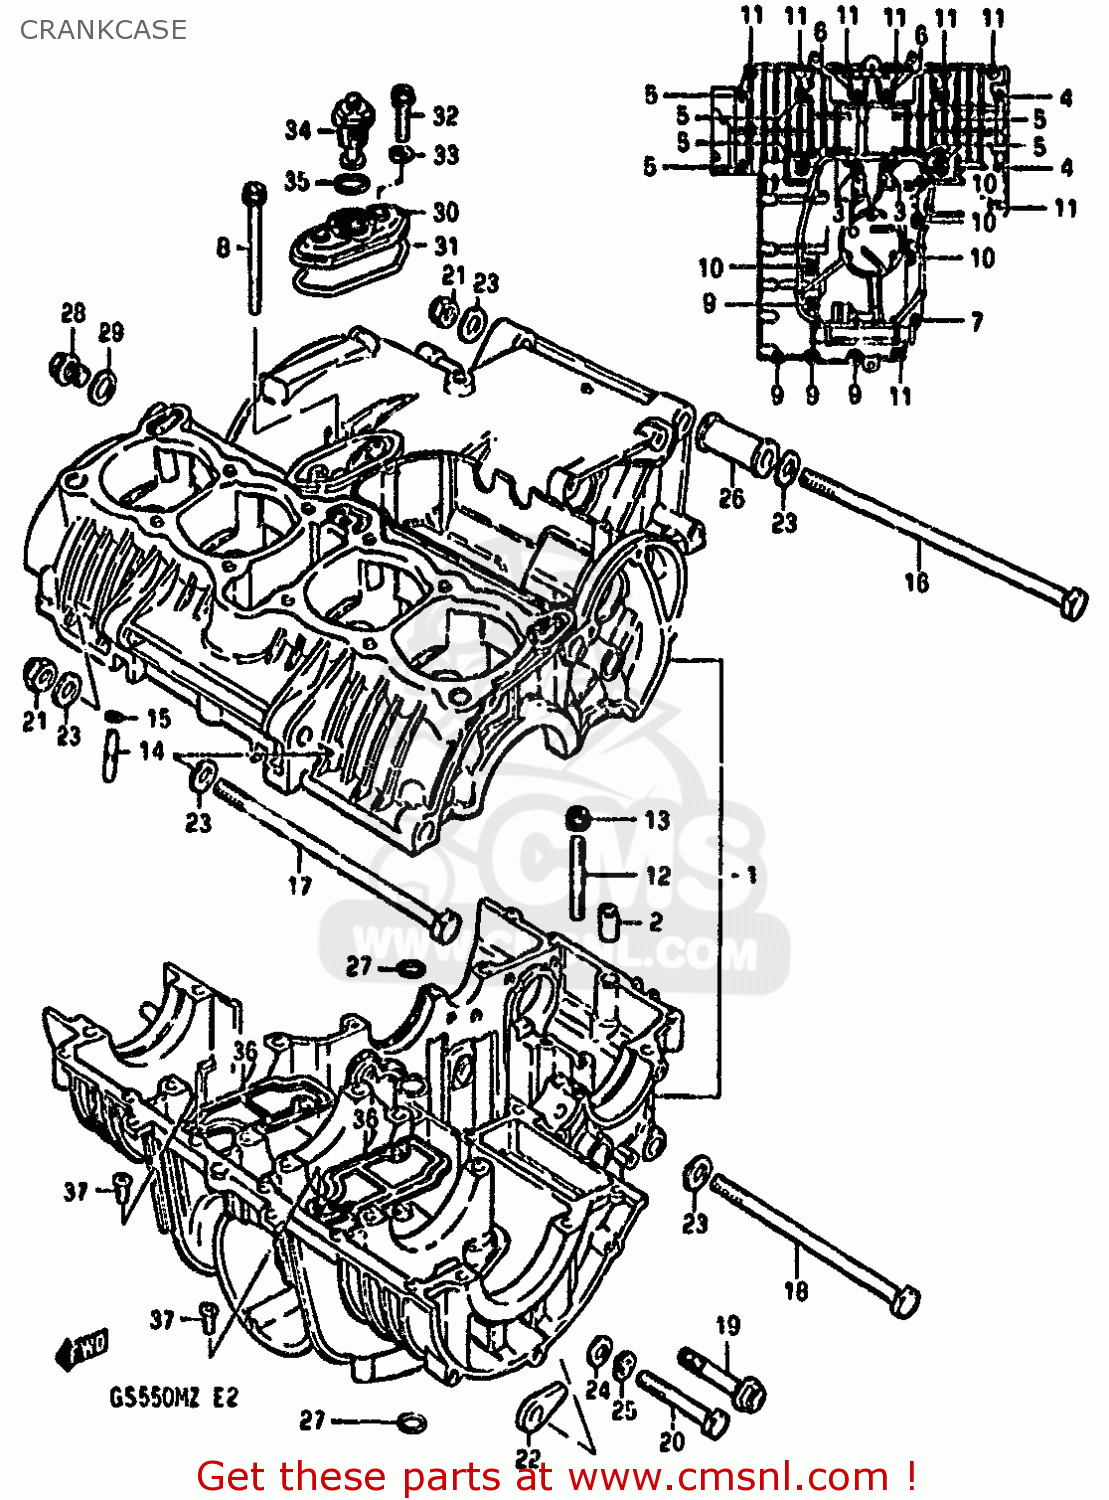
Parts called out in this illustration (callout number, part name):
1	CRANKCASE SET
2	PIN
3	BOLT
4	BOLT 8X90
5	BOLT (8X70)
6	BOLT 8X55
7	BOLT (8X45)
8	BOLT (6X90)
9	BOLT (6X60)
10	BOLT ,6X50
11	BOLT
12	STUD BOLT
13	NUT
14	UNION
15	O RING(D:1.05,ID:3.1)
16	BOLT 10X270
17	BOLT
18	BOLT(10X165)
19	BOLT 10X55
20	BOLT 10X55
21	NUT
22	NUT
23	WASHER
24	WASHER(10.5X20X3.2)
25	LOCK WASHER
26	SPACER,ENGINE MOUNT
27	O RING(D:3.2,ID:12.9)
28	PLUG (14X12)
29	GASKET(14X19.2X2) (NAS)
30	HOUSING,OIL PRESSURE SWITCH
31	O RING,PRESSURE SWITCH HOUSING
32	BOLT
33	GASKET (NAS)
34	SWITCH ASSEMBLY
35	O RING(D:1.9,ID:18.8)
36	PLATE,OIL SEPARATOR
37	SCREW
